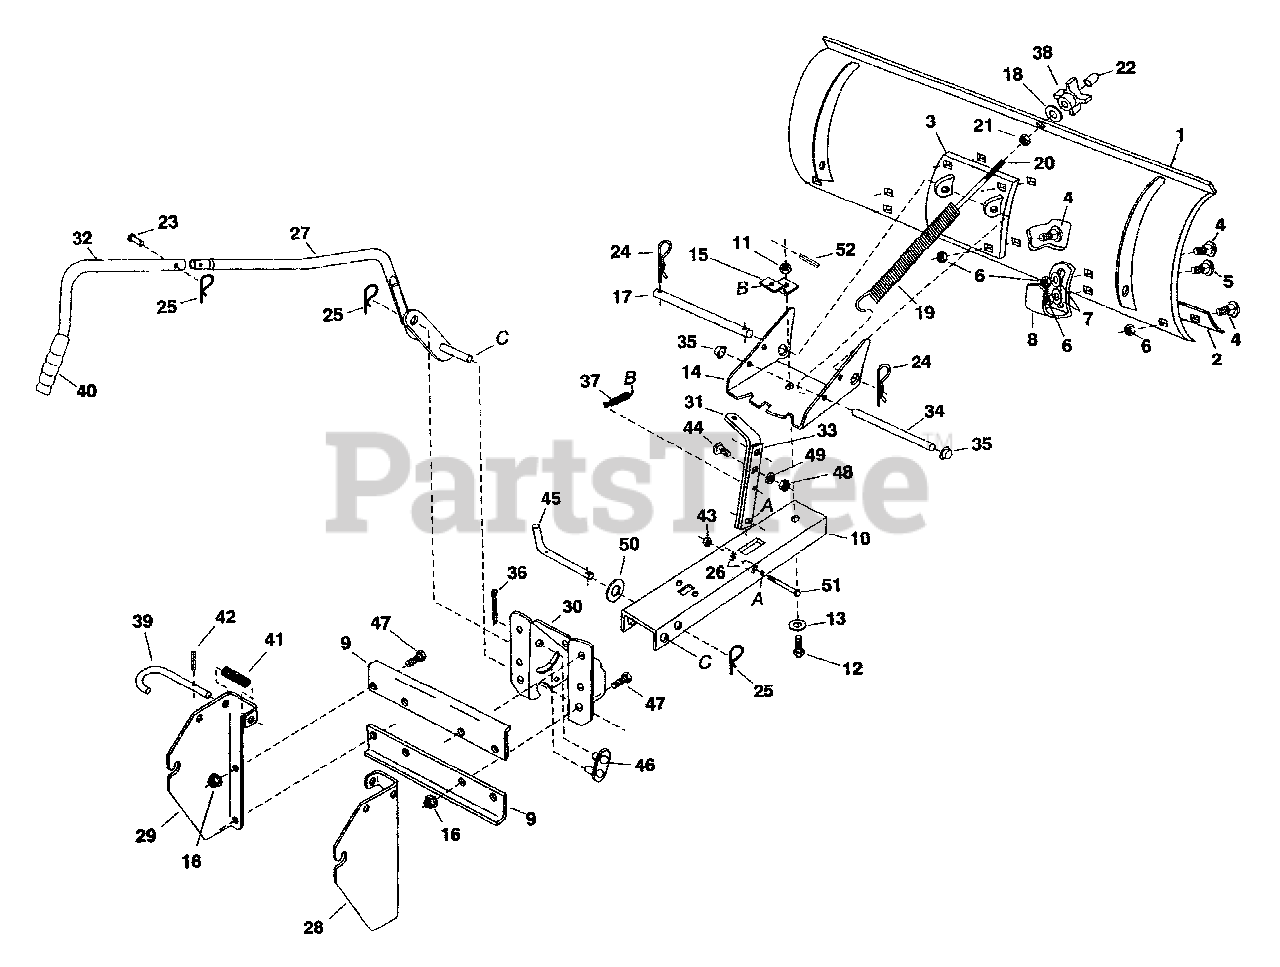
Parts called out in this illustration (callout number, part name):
1	Blade - 46"
2	Wear Plate - 46"
3	Reinforcement Plate Assy.
4	Bolt, Carriage 5/16-18 x 3/4"
5	Bolt, Carriage 5/16-18 x 1"
6	Hex Lock Nut, 5/16-18 Thd.
7	Washer, 5/16"
8	Skid Shoe
9	Bracket, Angle Support
10	Push Channel
11	Hex Lock Nut, 1/2 - 13 Thd.
12	Bolt, Special Pivot
13	Washer, Flat 1/2"
14	Plate, Pivot 7 Ga.
15	Bracket, Spring Mt.
16	Fl. Lock Nut, 3/8-16 Thd.
17	Shaft,. Pivot
18	Washer, 3/8" STD.
19	Spring, Blade Adjust
20	Hex Bolt, 3/8-16 x 3-1/2"
21	Hex Nut, 3/8-16 Thd.
22	Plastic Cap
23	Pin, Clevis 1/4" x 1-1/2"
24	Pin, Hair Cotter #4 (1/8")
25	Pin, Hair Cotter #3 (3/32")
26	Spacer, .28 ID x 1"
27	Lift Handle Assembly, Lwr.
28	Hitch Bracket, R.H.
29	Hitch Bracket, L.H.
31	Angle Lock Bar (Long)
32	Lift Handle, Upper
33	Angle Lock Bar (Short)
34	Spring Mount Rod
35	Palnut, 3/8"
36	Cotter Pin 1/8" x 1"
37	Angle Lock Spring
39	Pin, Attachment
40	Handle, Grip
41	Spring, Compression
42	Pin, Spring 3/16" x 1"
43	Hex Lock Nut, 1/4-20 Thd.
44	Carriage Bolt, 3/8-16 x 1-1/4"
45	Channel Pivot Pin
46	Lift Link Assembly
47	Hex Bolt, 3/8-16 x 1"
48	Hex Lock Nut, 3/8-16 Thd.
49	Lock Washer 3/8"
51	Hex Bolt, 1/4-20 x 3-1/4" Lg.Gr 5
52	1/4" x 1" Spring Pin
